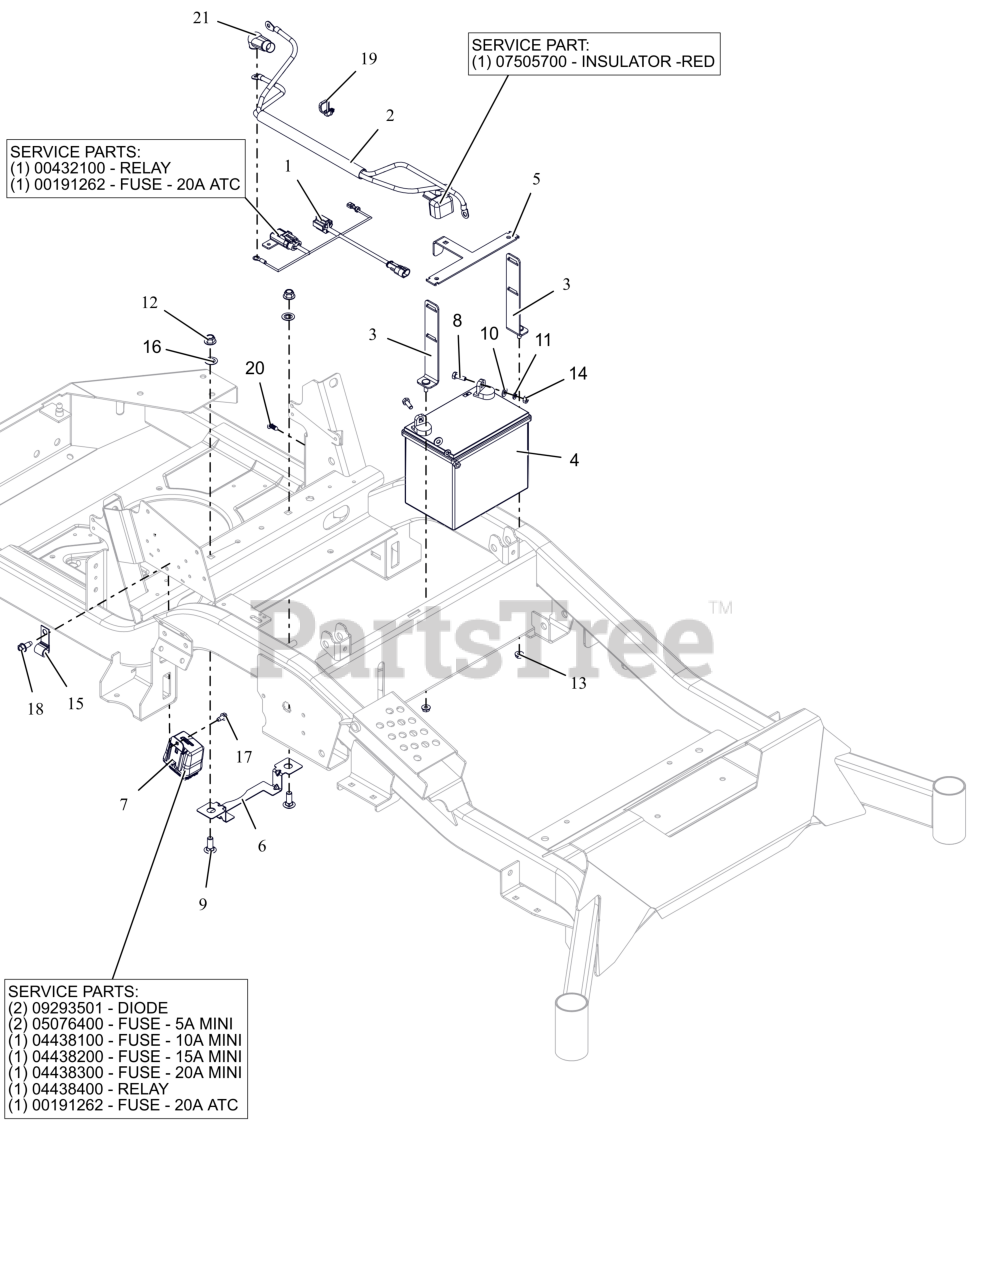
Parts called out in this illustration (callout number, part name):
1	HARNESS, STARTER ADAPTOR
1	RELAY,SEALED W/DIODE
1	FUSE, 20 AMP BLADE S/O
2	HARNESS, BATTERY HD
2	INSULATOR
3	WMT-BATT MNT HOLD DOWN FORMED
4	BATTERY, 300 CCA 10U1L
5	BRKT- BATTERY HOLD DOWN
6	GUARD, ELECTRICAL HARNESS
7	HARNESS, WIRE
7	DIODE, CONNECTOR SHELL
7	FUSE, 5 AMP MINI-ATC
7	FUSE,10 AMP MINI-ATC
7	Fuse, 15 AMP MINI-ATC
7	FUSE,20 AMP MINI ATC
7	RELAY,MICRO5 TERML W/RESISTOR
7	FUSE, 20 AMP BLADE S/O
8	BLT, HEX .25-20X.75 G5 ZCC
9	BLT, RHSN .38-16X1.00 G5 ZCC
10	WSHR,FLT .281X.625X.065 ZCC
11	WSHR,LK-REG .250X.062 ZCC
12	NUT,NYL-FLG .38-16 GF ZCC
13	NUT-LK-TOP-FLG .250-20 GF ZCC
14	NUT-STD .250-20 G2 ZCC
15	J-CLAMP
16	WSHR, RETAINING .35X.88X.03 NYL
17	SCR-TAP .25-20X.50 HWH ZCC
18	SCR,TAP .312-18X.75 HWH TR ZCC
19	CABLE TIE W/ TREE (.25 HOLE)
20	RIVET, .25 NYLON PANEL
21	BOOT, .65ID POS
